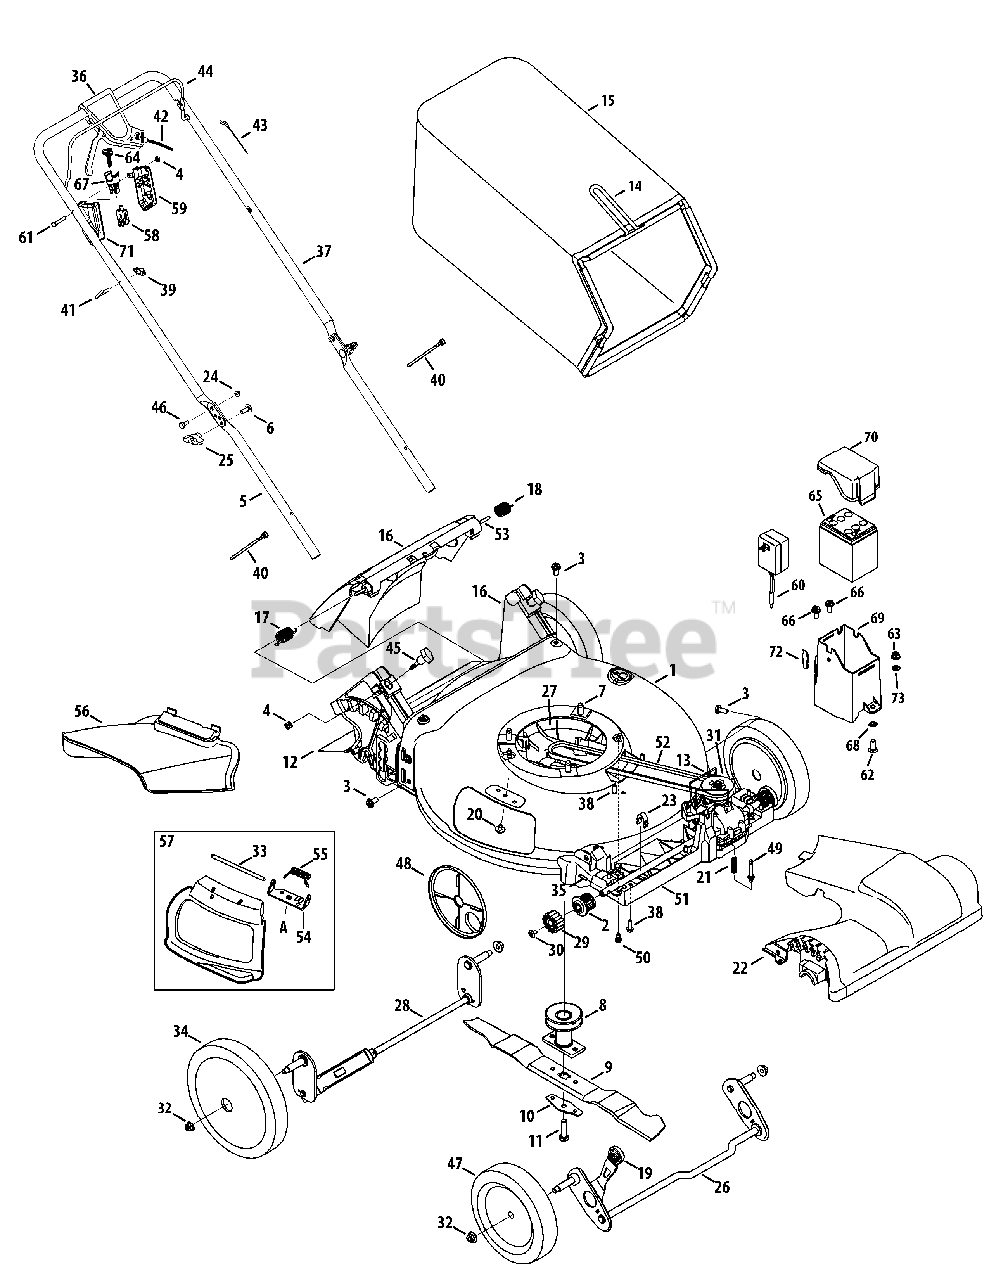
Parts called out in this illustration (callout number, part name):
1	Deck, 21"
2	Bearing Assembly
3	Screw, 5/16-14 x .750
4	Nut, Sq., 1/4-20
5	Lower Handle
6	Carriage Screw ,5/16-18
7	Screw, 3/8-16 x 1.00
8	Blade Adapter (159cc)
9	Mulching Blade
10	Blade Bell Support
11	Screw, 3/8-24 x 1.50
12	Trailing Shield
13	Transmission Wire
14	Grass Catcher Frame
15	Grass Bag, Remington
16	Rear Discharge Door Assembly
17	Torsion Spring - RH
18	Torsion Spring - LH
19	Adjustment Lever Knob (Orange)
20	Screw, 1/4-20 x .500
21	Compression Spring
22	Front Cover
23	Front Axle Clip
24	Nut, Flange Lock, 1/4-20
25	Wing Knob
26	Front Axle Assembly
27	Engine Baffle
28	Rear Axle Assembly
29	Spur Gear, 14T - RH
29	Spur Gear, 14T - LH
30	Screw, 1/4-20 x .390
31	Transmission Assembly
32	Flange Lock Nut, 3/8-16
33	Hinge Pin
34	Rear Wheel, 11", Oyster Gray
35	Dowel Pin
36	Control Lever Assembly
38	Screw, 1/4-15 x .750
40	Cable Tie
41	Rope Guide
42	Drive Cable
43	Control Cable (6X65RU)
45	Wing Nut, Orange
46	Sldr. Screw, .375 x .126 x 1/4-20
47	Front Wheel, Gray, Pin Bar
48	Wheel Dust Cover
49	Spring Body
50	Shoulder Screw, 1/4-20 x 0.50
51	Lower Tray
52	V-Belt
53	Pivot Rod
54	Chute Deflector Bracket
55	Torsion Spring
56	Side Discharge Chute
57	Mulch Plug (Incl. 33, 54-58)
58	Plunger Switch
59	Electric Start Housing, LH
60	Battery Charger
61	Screw, 1/4-20 x 1.75
62	Bolt, Carr., 5/16-18 x 1.00
63	Nut, Hexlk, 5/16-18
65	Battery
66	Scr., Sldr., 5/16-14 x .972
67	Key Switch
68	Speed Nut
69	Battery Housing
70	Battery Housing Top
71	Electric Start Housing, RH
72	Lid Seal
73	Washer, Bell, .340 x .872 x .080
